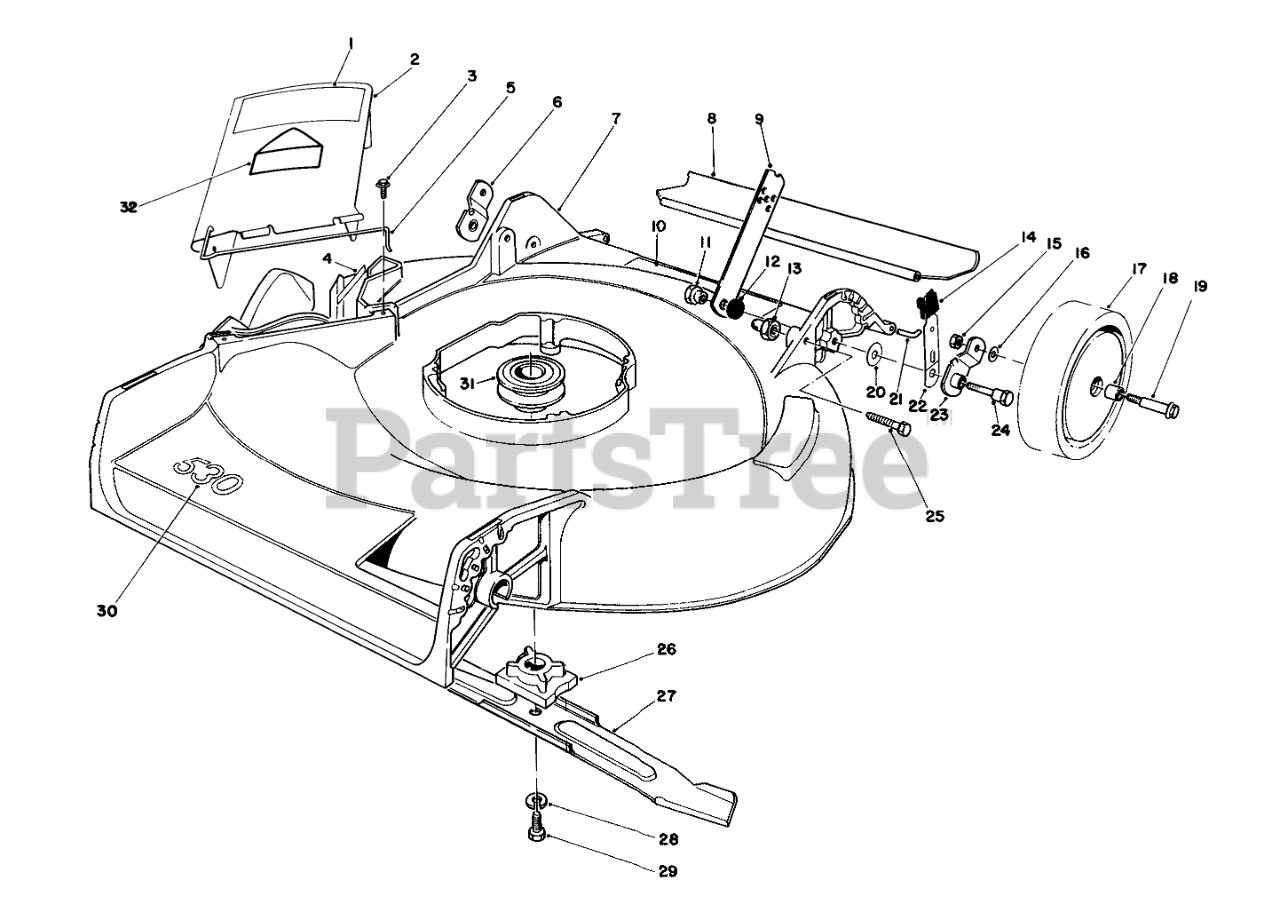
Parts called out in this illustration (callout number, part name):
1	DANGER DECAL
2	Deflector Assembly (Incl. Ref. #1, 5 & 32)
3	SCREW-HWH
4	Decal-Danger
5	SPRING HINGE
6	Pivot Arm
7	Housing
8	REAR SAFETY SHIELD 21
9	HANDLE LATCH
10	DECAL-DANGER
11	HANDLE PIVOT NUT
12	SPACER
13	HANDLE PIVOT NUT
14	KNOB-ARM
15	Nut
16	WASHER
17	Wheel & Tire Assembly (Incl. Ref. # 18)
18	BUSHING
19	BOLT-WHEEL
20	WASHER-PIVOT
21	SHIELD ROD
22	SPRING ARM ASM
23	Pivot Arm
24	PIVOT SCREW
25	SCREW-HH
26	BLADE RETAINER
27	Blade
28	WASHER-LOCK
29	SCREW-HH
30	Decal-530
31	PULLEY-DRIVER
32	DECAL-DANGER
